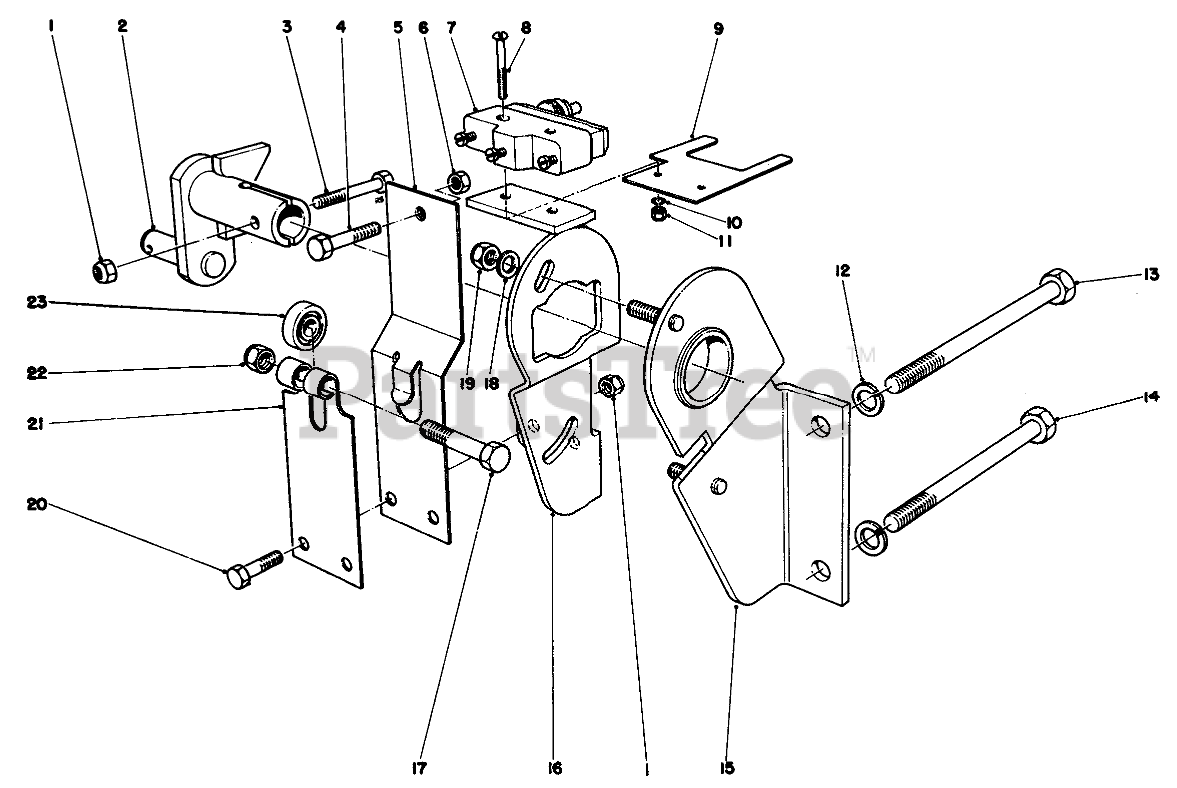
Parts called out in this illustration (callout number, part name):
1	NUT-LOCK, NI
2	Lever-Pump
3	SCREW-HH
4	SCREW-HH
5	EXTENDED LEAF SPRING ASM
6	NUT-HEX
7	Micro Switch
8	SCREW-MACHINE
9	STOP-SPRING, LEAF
10	WASHER-LOCK, INTERNAL
11	NUT-HEX
12	WASHER-LOCK
13	SCREW-HH
14	SCREW-HH
15	MTG BRKT WA B
16	PUMP PLATE WA B
17	SCREW-HH
18	Washer-Thrust
19	NUT-LOCK
20	SCREW-HH
21	SPRING-LEAF
22	NUT-LOCK, NI
23	BEARING-BALL
